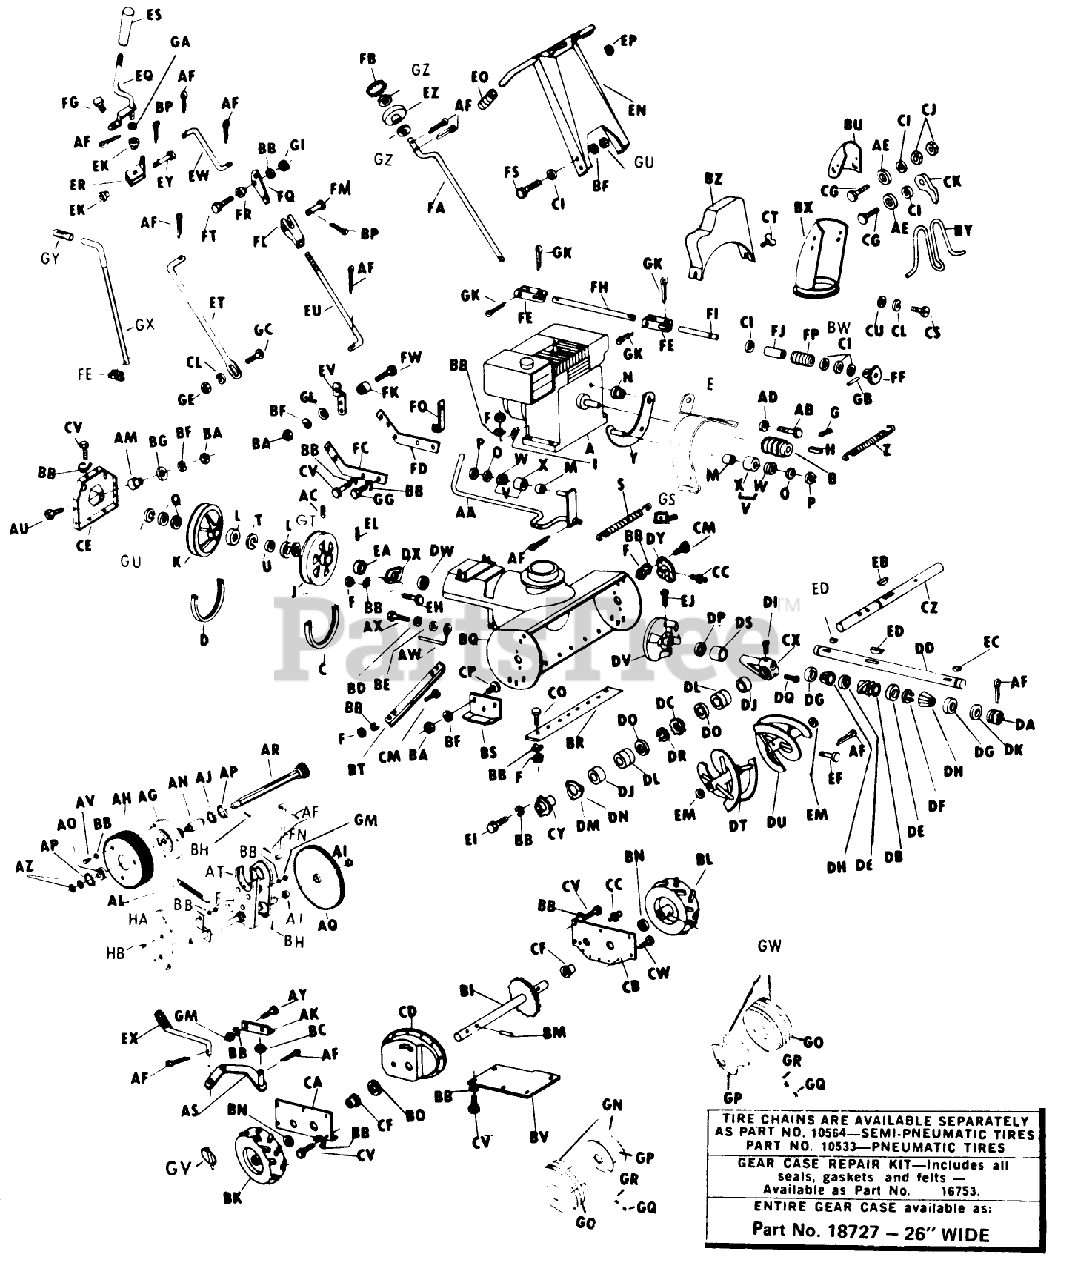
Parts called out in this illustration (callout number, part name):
A	Engine-5 H.P.-BS Model 130202-0237-02
B	Engine Pulley
AQ	Countershaft Gear Assembly
BQ	Auger Wrap Main Frame Assembly
BU	Deflector
CX	Gear Case
EN	Handle Bar Assembly
FF	Sprocket Assembly
